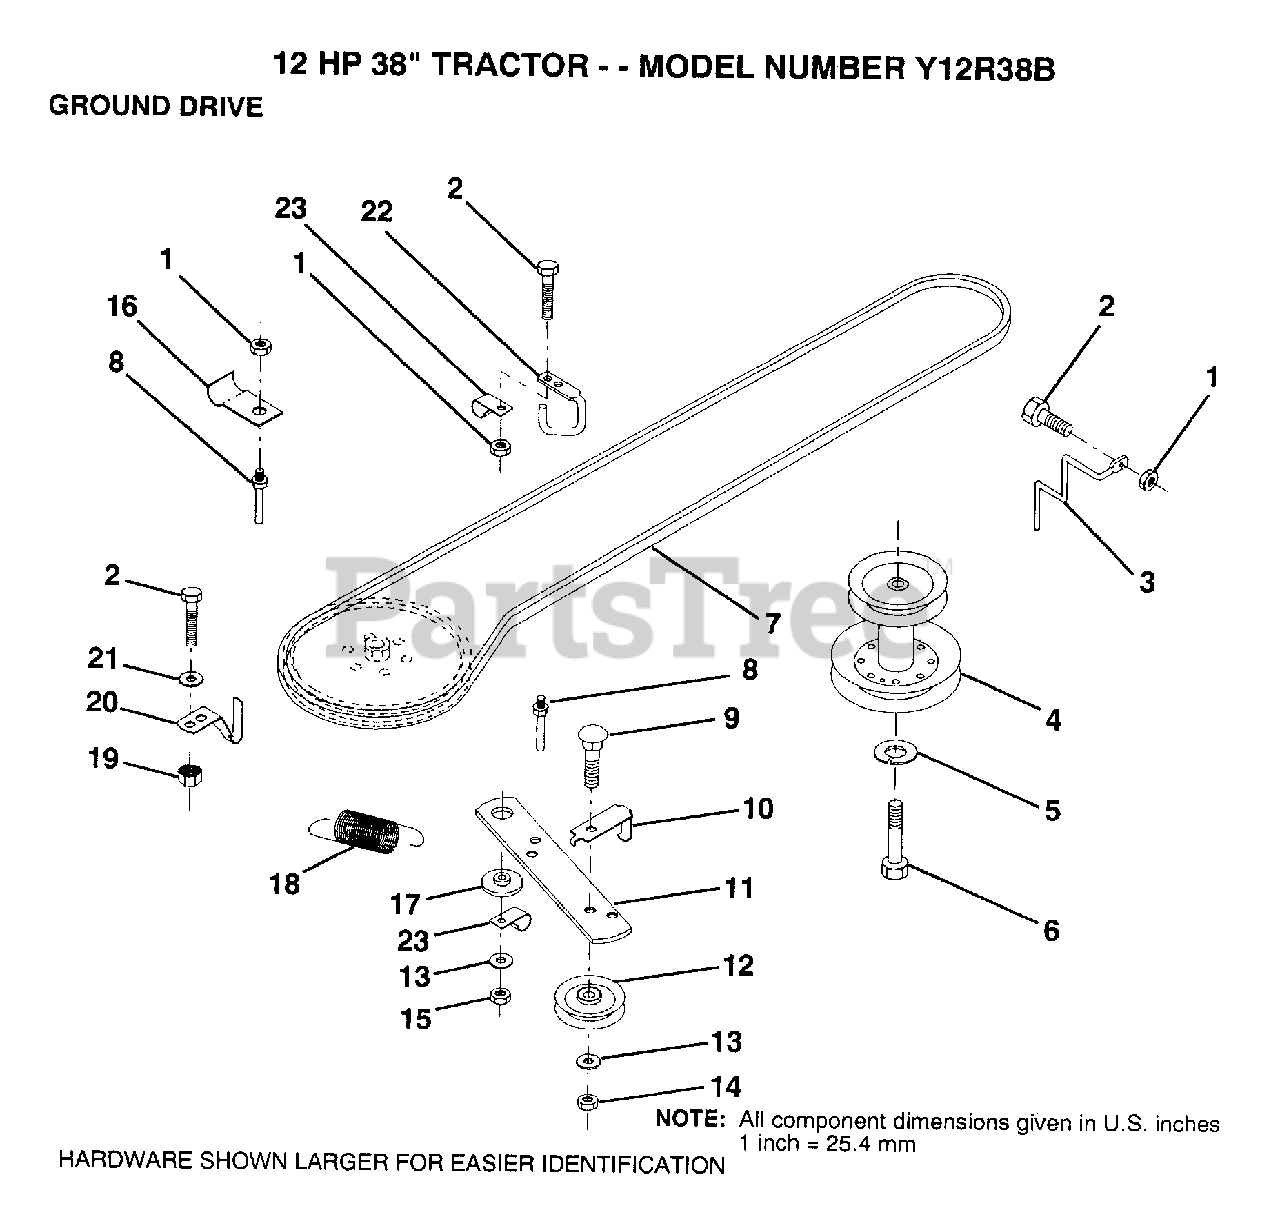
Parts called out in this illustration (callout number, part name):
2	BOLT
3	KEEPER MWR DR BLT
5	LOCKWASHER
6	BOLT
7	BELT
8	"KEEPER,DRIVE BELT"
9	BOLT
10	"KEEP,IDLER DR BEL"
13	WASHER
14	LOCKNUT
16	"CLIP,INSULATOR"
17	SPACER RETAINER
20	"KEEPER,DR BELT "
21	WASHER
22	"KEEPER,FRA DR BEL"
23	CLIP INSULATOR
